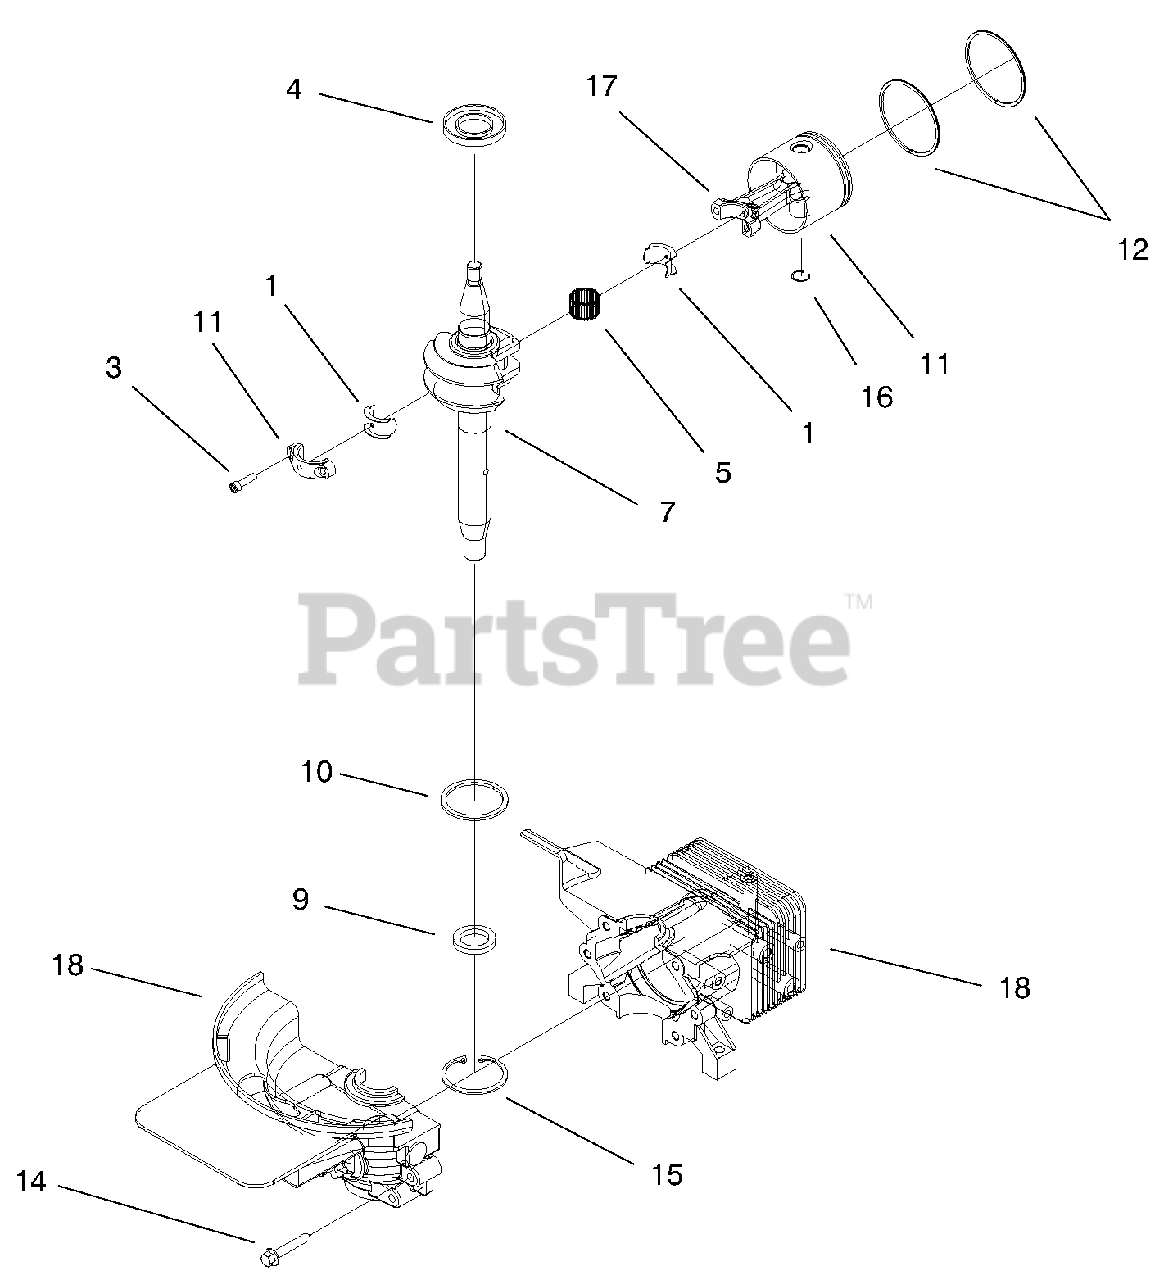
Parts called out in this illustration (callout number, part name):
1	Split Liner ASM
4	Oil Seal
5	Needle Bearing
7	Crankshaft & Bearing ASM
9	Oil Seal
10	Ring Retaining
11	Piston & Conn Rod ASM
12	Ring Set
14	Screw-HWH
15	Ring-Retaining
16	Ring-Retaining
17	Connecting Rod ASM
18	Cylinder & Crankcase ASM
